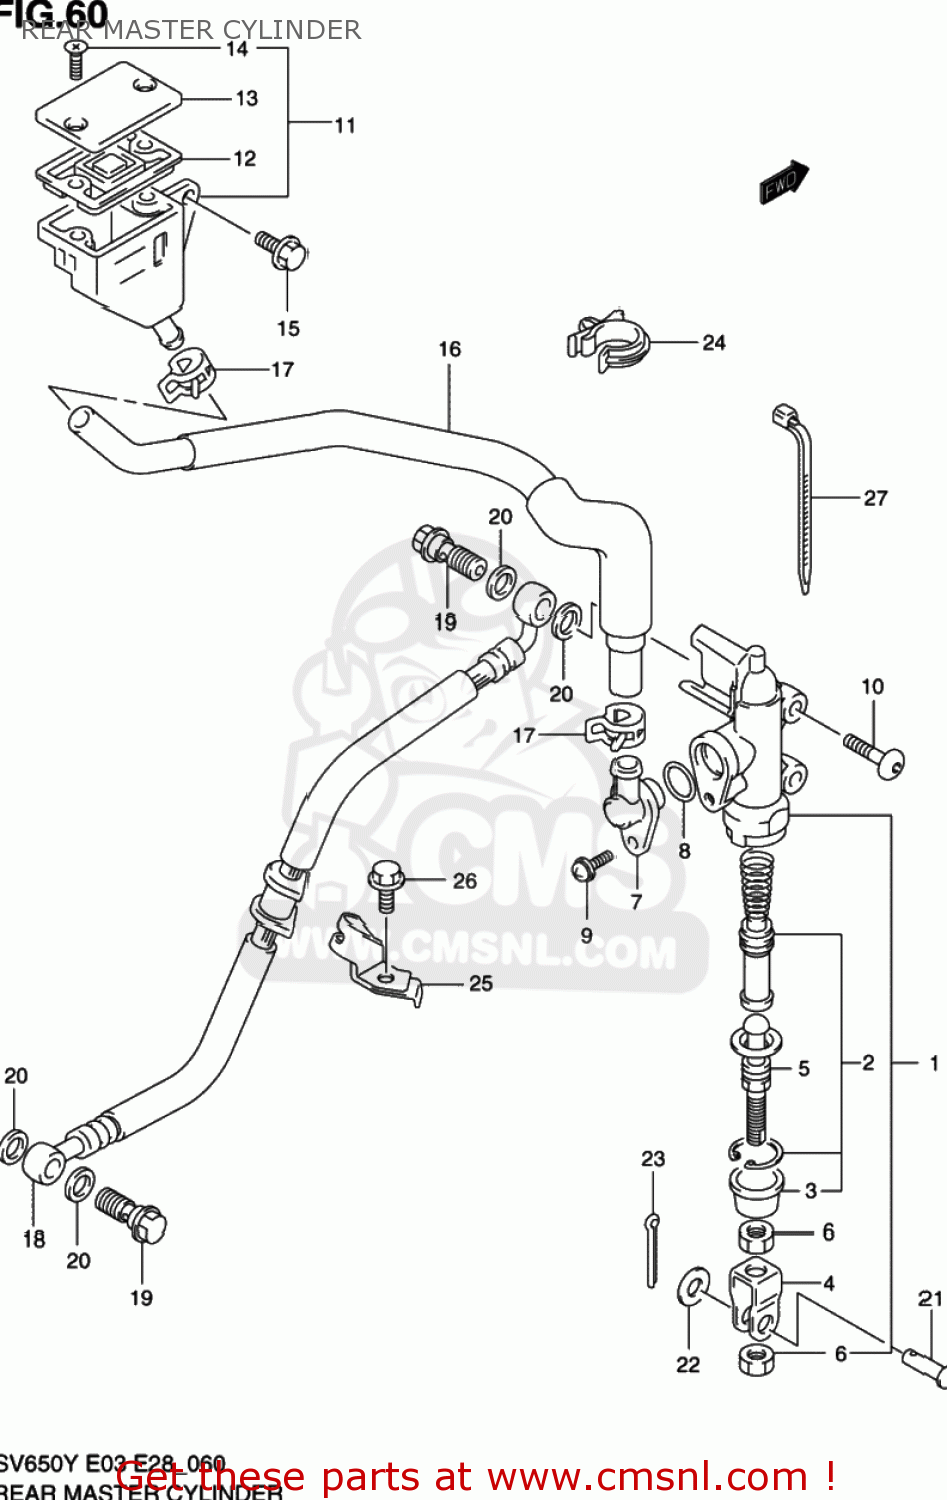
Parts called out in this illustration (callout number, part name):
1	CYLINDER ASSY,RR MASTER
2	PISTON/CUP SET
3	BOOT
4	YOKE
5	ROD,PUSH
6	NUT
7	CONNECTOR
8	O RING
9	SCREW
10	SCREW(6X20)
11	TANK ASSY,RR RESERVOIR
12	DIAPHRAGM
13	CAP
14	SCREW
15	BOLT
16	HOSE,RR RESERVOIR TANK
17	CLIP
18	HOSE, REAR BRAKE
19	BOLT UNION
20	WASHER(10X15X1.5)
21	PIN
22	WASHER
23	PIN
24	CLAMP
25	CLAMP,RR BRAKE HOSE
26	BOLT
27	CLAMP(L:165)
